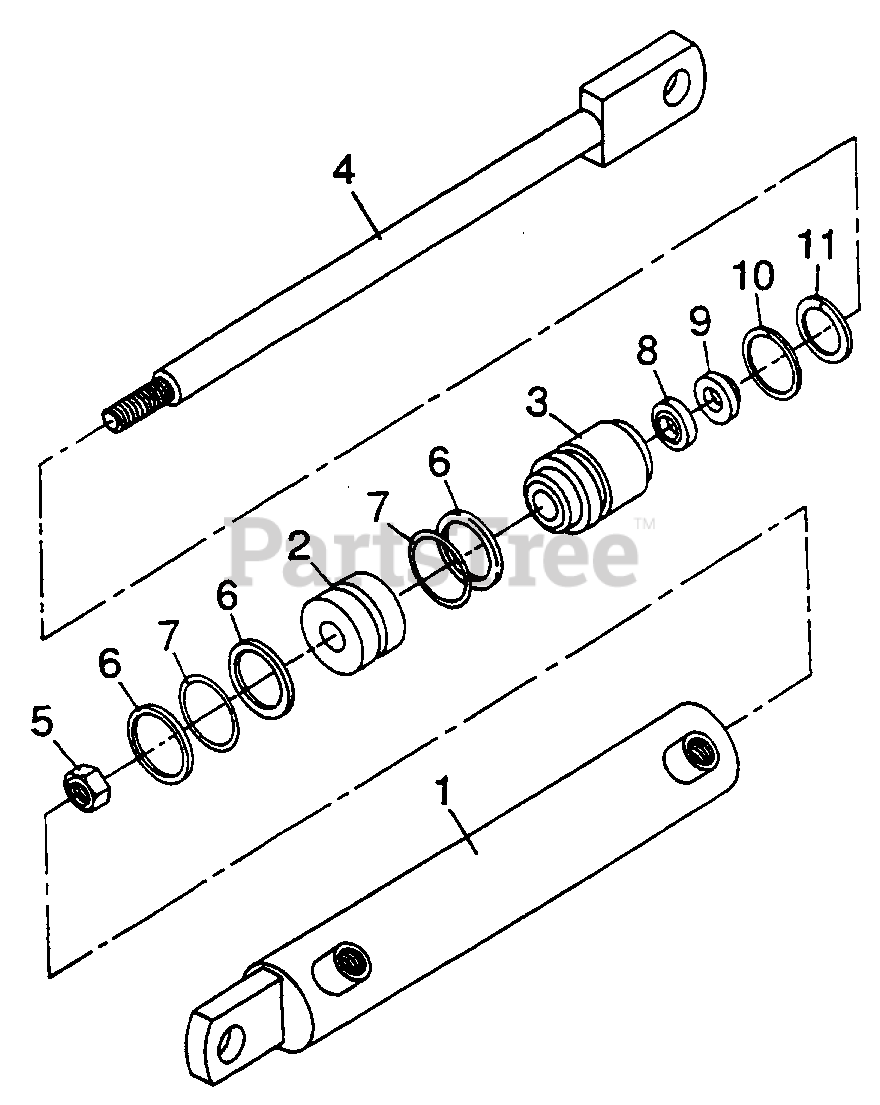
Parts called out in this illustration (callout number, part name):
1	Cylinder body 1.5 ID w/c
2	Piston, alum 1-1/2 O.D.
3	Guide 1-1/2 O.D.-3/4 I.D.
4	Rod .75 Dia w/c
5	1/2-20 Locknut
6	1.25 x 1.50 Backup ring
7	1-1/4 x 1-1/2 O-Ring
8	.25 x .75 x 1.000 U-cup lip
9	3/4 Wiper ring
10	1-1/2 Internal retaining ring
11	1-5/16 External retaining ring
